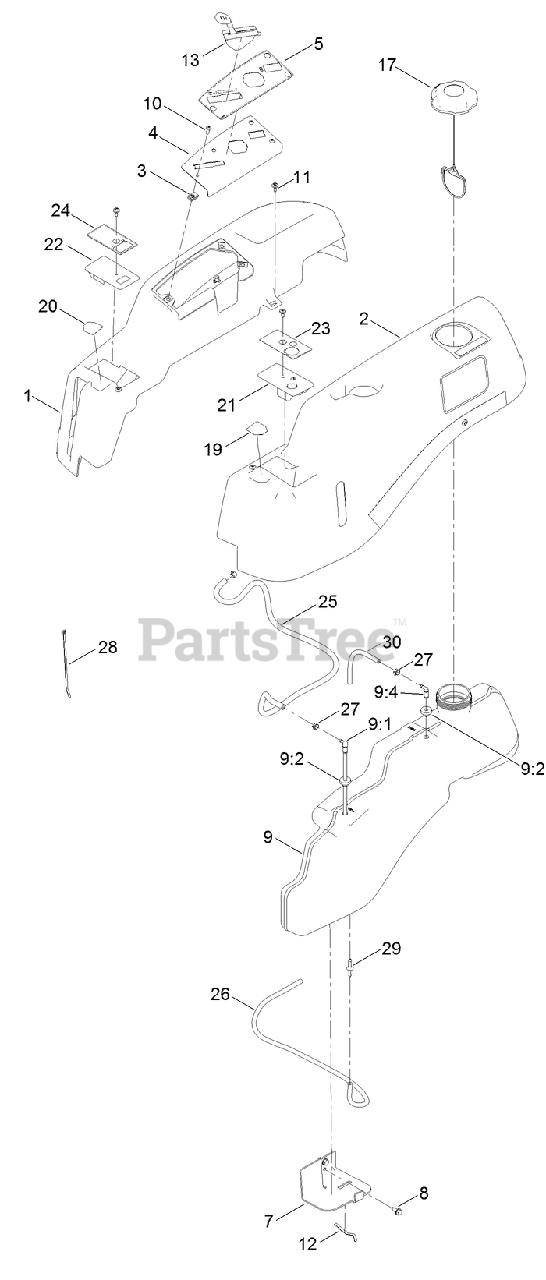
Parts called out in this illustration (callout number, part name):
1	POD-RH
2	POD-LH
4	PLATE-CONTROL
5	DECAL-PANEL, CONTROL
7	SUPPORT-TANK, FRONT
8	SCREW-HWHTF
9	FUEL TANK ASM
9:1	CONNECTOR-ELBOW, 90 DEG
9:2	BUSHING
9:4	FITTING-PLASTIC
10	SCREW-PRH
11	SCREW-SHOULDER
12	SPRING
13	CABLE-THROTTLE AND CHOKE
17	CAP-FUEL, RATCHETING
19	DECAL-NMIR
20	DECAL-CONTROL, PEDAL
21	COVER-LH
22	COVER-RH
23	DECAL-KEYCHOICE
24	DECAL-BRAKE, PARKING
25	HOSE-FUEL
26	HOSE-FUEL
27	CLAMP-HOSE
28	TIE-CABLE
29	ADAPTOR-ORIFICE
30	HOSE-FUEL
